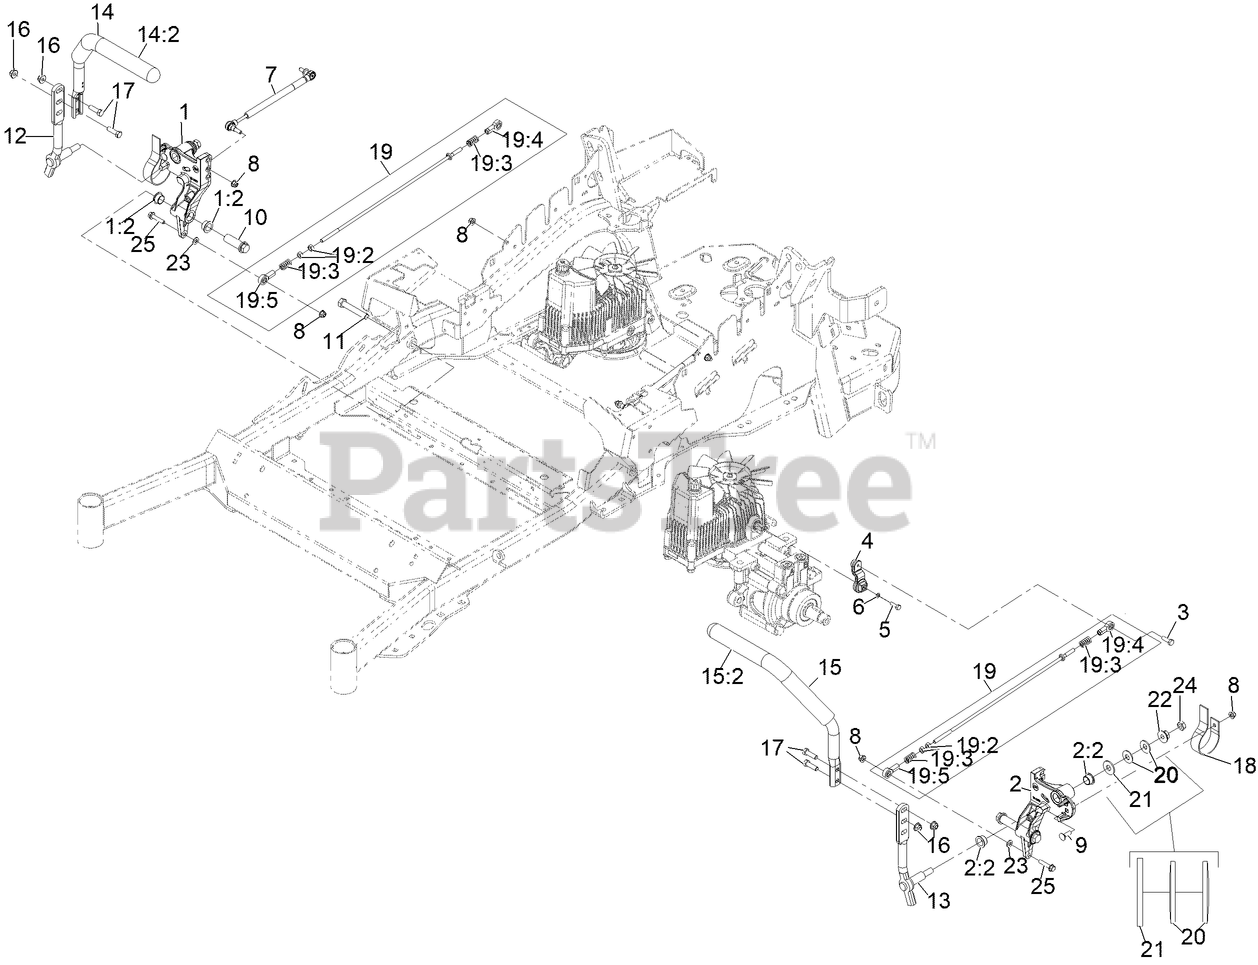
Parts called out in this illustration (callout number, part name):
1	RH MOTION CONTROL AND BUSHING ASM
1:2	BUSHING-FLANGE
2	LH MOTION CONTROL AND BUSHING ASM
2:2	BUSHING-FLANGE
3	SCREW-HH, THREAD LOCKING
4	ARM-CONTROL, PUMP
5	SCREW-HH
6	WASHER-SPRING
7	DAMPER-CONTROL, MOTION
8	NUT-HF, NI
9	BOLT-CARR
10	HUB-THREADED
11	SCREW-HH
12	LEVER-CONTROL MOTION, RH
13	LEVER-CONTROL MOTION, LH
14	RH HANDLE ASM
14:2	GRIP-LEVER, CONTROL
15	LH HANDLE ASM
15:2	GRIP-LEVER, CONTROL
16	NUT-HF, NI
17	SCREW-HH
18	SPRING-LEAF
19	FRONT PUMP LINKAGE ASM
19:2	NUT-HEX
19:3	SPRING-COMPRESSION
19:4	BALLJOINT-LH
19:5	BALLJOINT-RH
20	WASHER-SPRING
21	WASHER-FLAT
23	WASHER-PLAIN
24	NUT-JAM
25	SCREW-HHF
